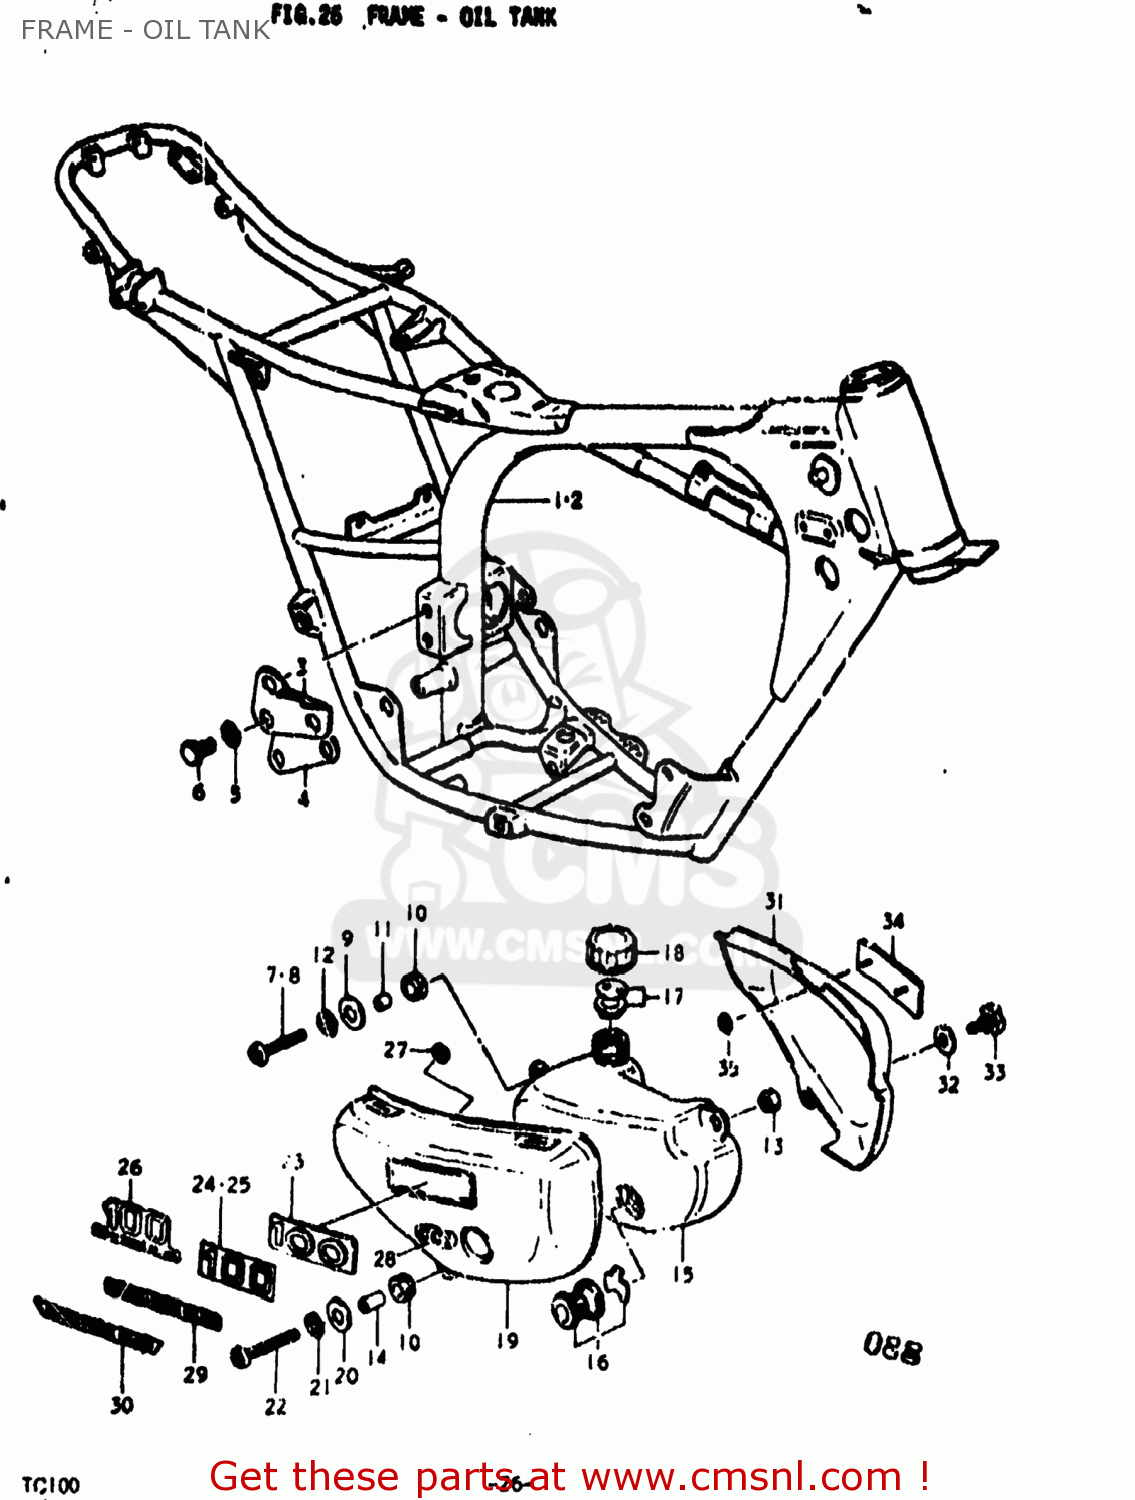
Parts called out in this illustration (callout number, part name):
1	FRAME
2	FRAME
3	PLATE,ENGINE MOUNTING
4	PLATE,ENGINE MOUNTING
5	LOCK WASHER
6	BOLT
7	SCREW
8	SCREW
9	WASHER
10	CUSHION
11	SPACER (6.8X10X10)
12	LOCK WASHER
13	NUT
14	SPACER
15	TANK,OIL
16	LENS SET,OIL LEVEL
17	LENS,OIL LEVEL INSPECTION
18	CAP,OIL TANK
19	COVER,FRAME,RIGHT
20	WASHER
21	LOCK WASHER
22	SCREW
23	EMBLEM,FRAME COVER
24	EMBLEM
26	EMBLEM
27	NUT
28	EMBLEM,CCIS
29	LABEL,COMPANY NAME
30	LABEL (COMPANY NAME)
31	COVER,FRAME,LEFT
32	NUT (5MM)
33	KNOB,FRAME COVER
34	EMBLEM,FRAME COVER
35	NUT
